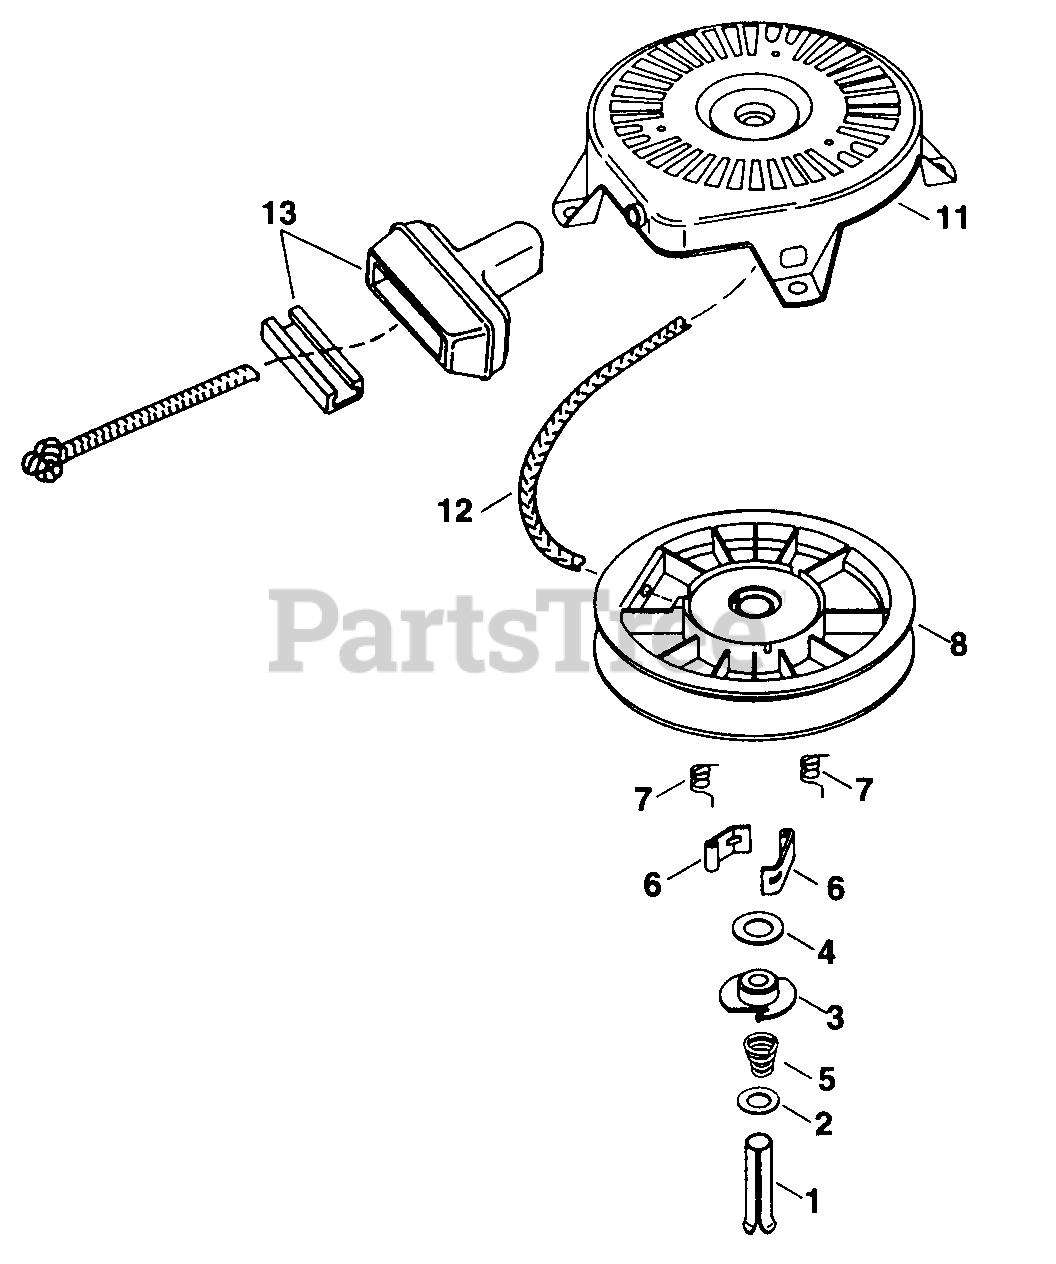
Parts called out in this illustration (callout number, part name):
1	Spring Pin
5	Brake Spring
6	Starter Dog
7	Dog Spring
8	Pulley 8 Rewind Spring Ass'y.
11	Starter Housing Ass'y.
12	Starter Rope (Length 114" x 11/64" Dia.)
13	Starter Handle
